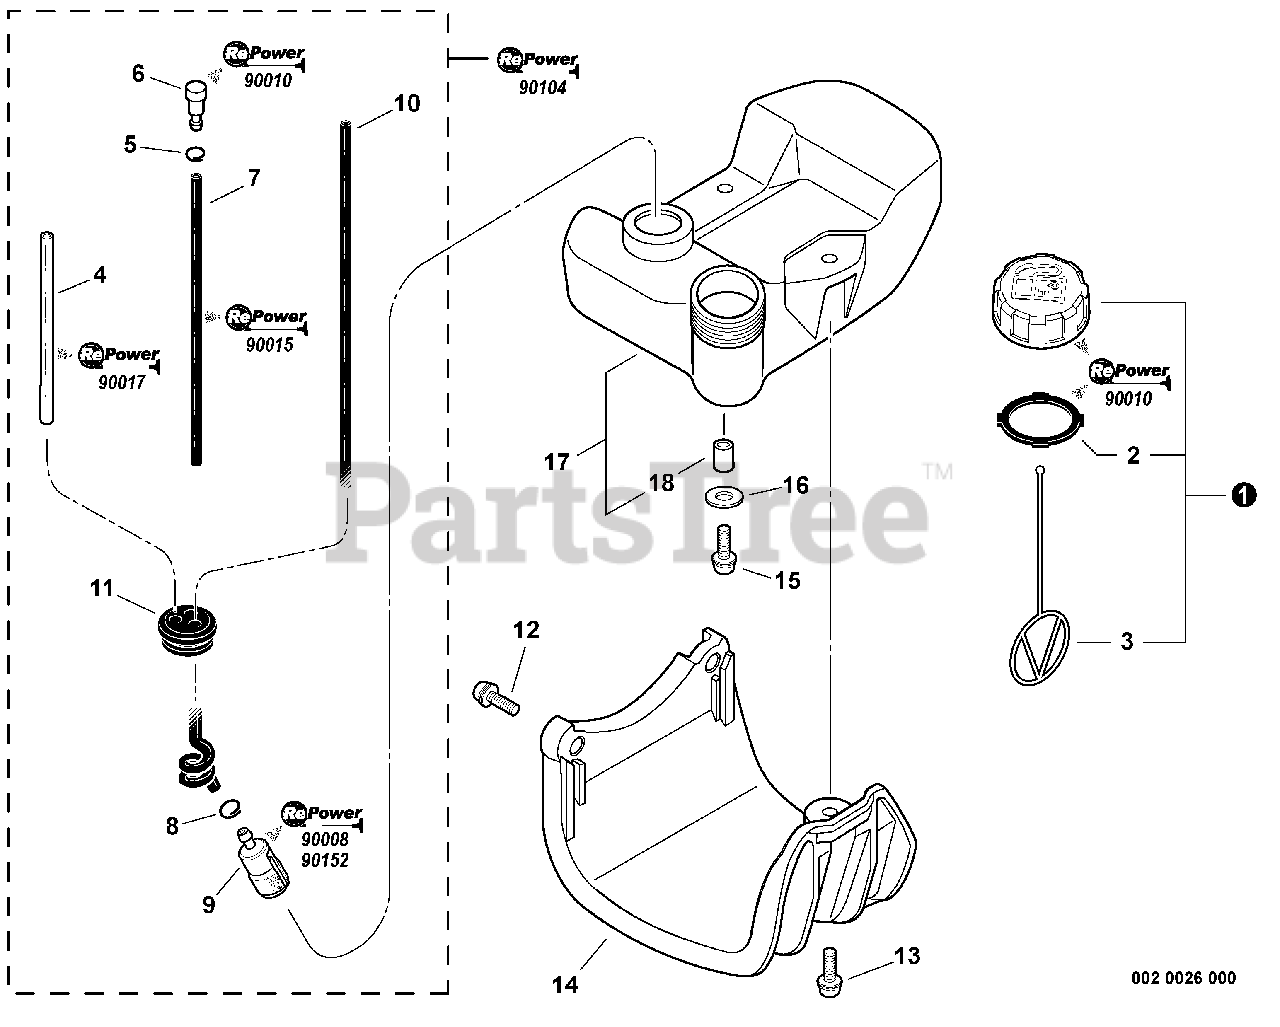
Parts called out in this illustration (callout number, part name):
1	CAP ASSY, FUEL
2	GASKET, FUEL CAP
3	CONNECTOR, CAP L= 100 MM
4	PIPE, FUEL 3×6×80 CLEAR
5	CLIP Ø6.5 MM
6	VENT ASSY
7	PIPE 3×6×115 BLACK
8	CLIP Ø6.5 MM
9	FILTER, FUEL
10	PIPE, FUEL 3×6×165
11	GROMMET, FUEL
12	BOLT 5×22
13	SCREW 5×20
14	GUARD, FUEL TANK
15	BOLT 5×16
16	WASHER 5.5×12×0.8
17	TANK, FUEL
18	SPACER 6.2×7.8×6
19	FUEL SYSTEM KIT
20	TUNE-UP KIT - REPOWER
21	FILTER KIT - REPOWER
22	CAP/VENT KIT - REPOWER
23	BULK PIPE - 3×6 MM BLACK (4 PIECES×2 M)
24	BULK PIPE - 3×6 MM CLEAR (4 PIECES×2 M)
